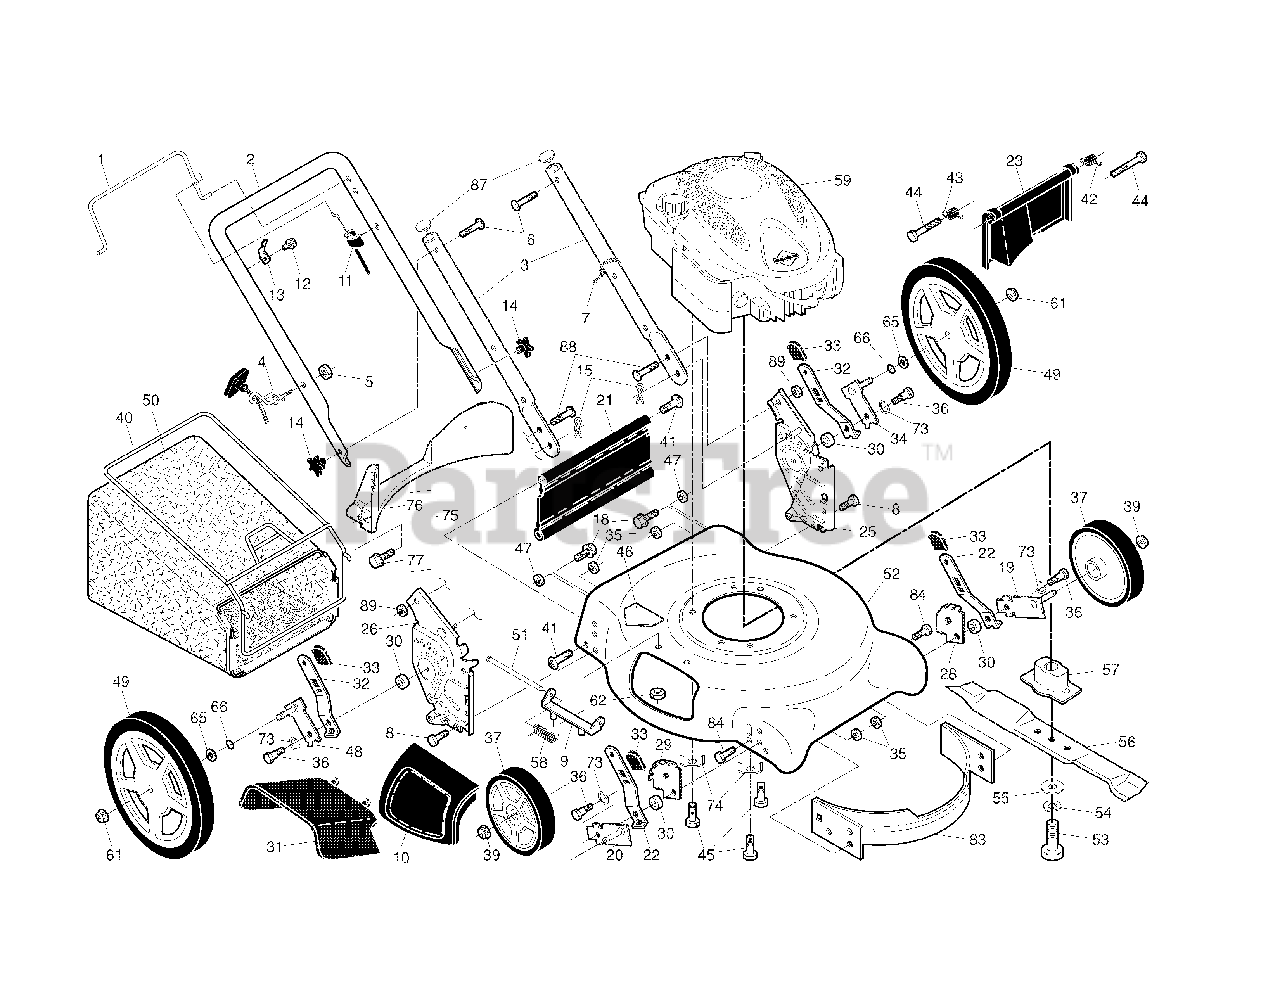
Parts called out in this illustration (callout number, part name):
1	CONTROL BAR
2	UPPER HANDLE
3	BAR, LOWER HANDLE
4	Rope Guide
5	Nut, Hex
6	Handle Bolt
7	Wire Tie
8	Bolt, Hex Head 5/16-18 x 3/4
9	Hinge Bracket
10	Mulcher Door
11	ENGINE ZONE CONTROL CABLE
12	SCREW, HEX WASHER HEAD
13	UP-STOP BRACKET
14	Handle Knob
15	Hairpin Cotter
18	SCREW.HEX.WASHEAD.1/4-20 X 3/8
19	Axle Arm Assembly, Front, LH
20	Axle Arm Assembly, Front, RH
21	Kit, Rear Skirt
22	Selector Spring, Front
23	Rear Door Assembly
25	HANDLE BRACKET ASSEMBLY, LH
26	HANDLE BRACKET ASSEMBLY, RH
28	Wheel Adjusting Bracket, LH
29	Wheel Adjusting Bracket, RH
31	Discharge Deflector
32	SELECTOR SPRING, REAR
33	Selector Knob
34	Axle Arm Assembly, Rear, LH
35	Locknut, Hex 5/16-18
36	Shoulder Bolt
37	WHEEL & TIRE ASSEMBLY, FRONT
39	Nut, Hex
40	Frame, Grassbag
41	HINGE SCREW
42	Spring, Rear Door, LH
43	Spring, Rear Door, RH
44	Bolt, Rear Door
45	Screw, Hex Head, Threaded, Rol
46	Danger Decal
47	Nut, Hex
48	Axle Arm Assembly, Rear, RH
49	WHEEL & TIRE ASSEMBLY, REAR
50	Grassbag
51	Hinge Rod
52	KIT, LAWN MOWER HOUSING
53	Screw, Hex Head, Grade 8 3/8-2
54	Helical Lockwasher
55	Hardened Washer
56	21" Blade
57	BLADE ADAPTER
58	Hinge Spring
61	Flanged Locknut, Hex
62	Locknut, Hex 1/4-20
65	Washer, Flat
73	Washer, Curved, Cylindrical
74	Washer, Special, Engine
75	Kit, Rear Baffle (Includes 3 S
76	Baffle, Rear
77	Screw, Rear Baffle
83	BAFFLE, FRONT
84	BOLT.5/16-18HEX.WHS.HD.LCKSERR
87	PLUG, HANDLE BAR
88	BOLT, CARRIAGE 5/16-18 X 5/8
89	Nut, Hex, Flangelock
